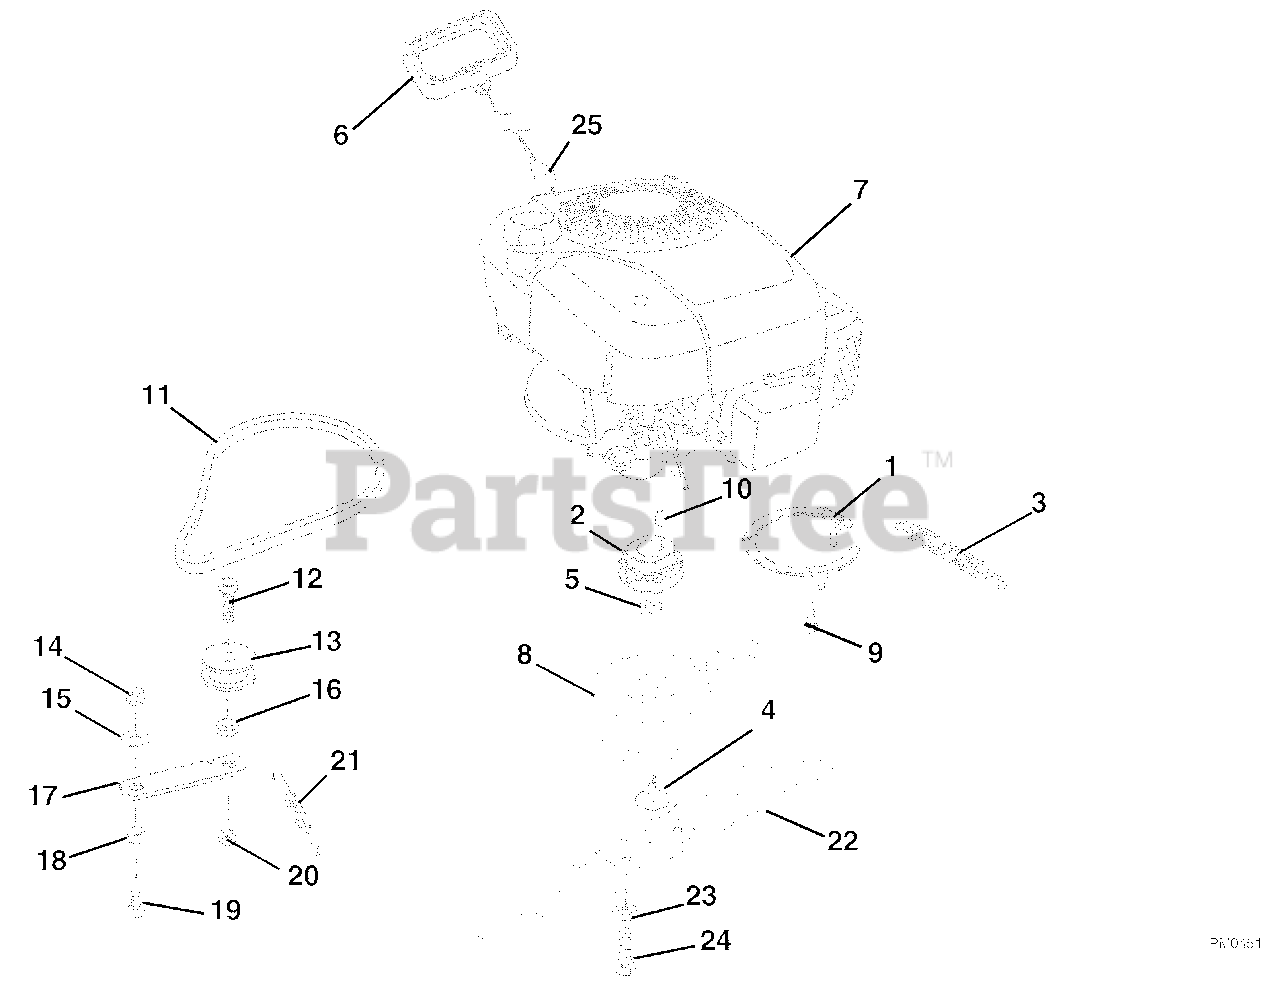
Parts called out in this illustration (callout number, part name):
1	BRACKET - SPRING RETAINER
2	PULLEY-SINTERED IRON LM
3	SPRG-TENS
4	SCR-SKH-SPECIAL .375-24X1.50
5	WASHER-WAVE .885X1.311X.125
6	HANDLE, RECOIL START
7	ENGINE, 6.75HP B&S INTEK - BBC
8	BLADE BRAKE CLUTCH
9	@SCR-TAP .38-16X1.00 HWH TR YZ
10	KEY-WDRF .156X.625X.25 SAE 6
11	V-BELT, 3L-COGGED
12	@BLT-HEX .44-14X1.50 GR5 YWZC
13	IDLER-FLAT 1.75 X .47
14	@NUT-LK-CTR .31-18 YWZC
15	@WSHR-FL-STL.344X.688X.065YWZC
16	BSHG-SLV .469 X .750 X .430
17	IDLER ARM
18	BSHG-FLG .325X.501X.250X1.120
19	@BLT-HEX .31-18X.75 GR5 YWZC
20	@NUT-LK-CTR .44-14 YWZC
21	SG-TENS .043X.44X3.31 WLD 5.8
22	21" BLADE - BBC
23	@WSHR-LK .44X.109 REG YWZC
24	BLT-HEX M10 X 1.5X25 YWZC
25	ROPE STOP
